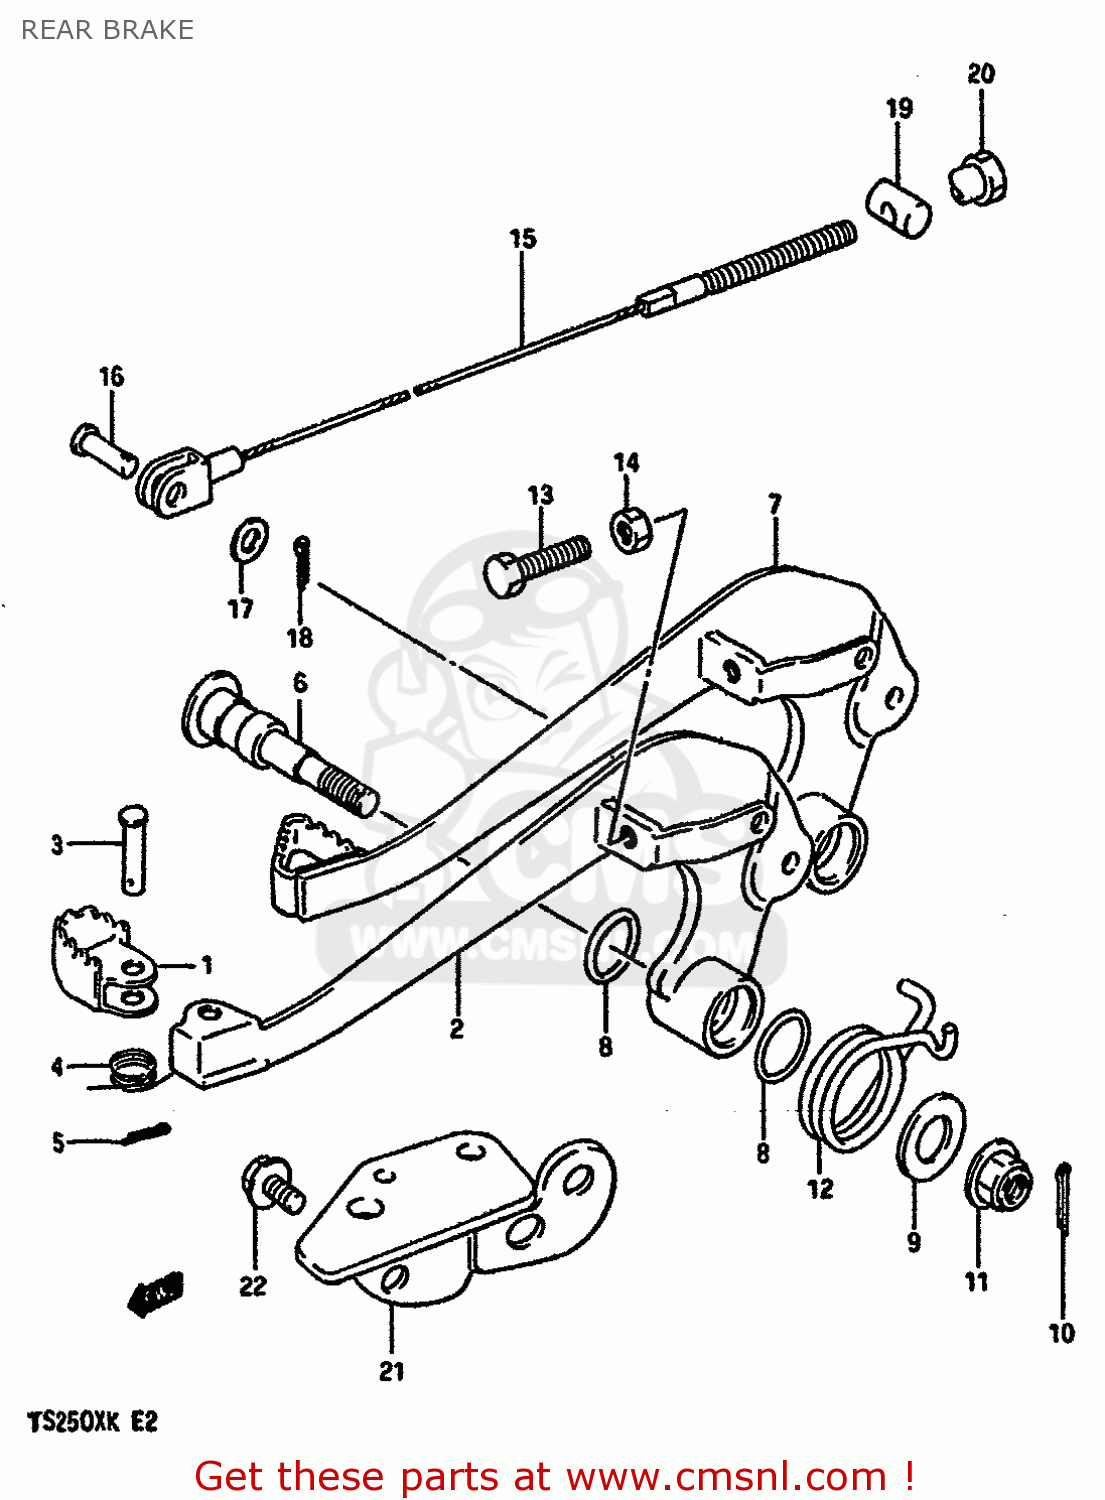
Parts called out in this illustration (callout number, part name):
1	PEDAL,BRAKE
2	ARM,BRAKE PEDAL
3	PIN
4	SPRING
5	PIN
6	SHAFT,BRAKE PEDAL
7	PEDAL,BRAKE
8	O RING(D:1.9,ID:14.5)
9	WASHER 10MM
10	PIN 20X20
11	NUT
12	SPRING
13	BOLT(6X23)
14	NUT 6MM
15	CABLE,REAR BRAKE
16	PIN(L:17.5)
17	WASHER
18	PIN 20X20
19	PIN(11X18)
20	NUT (6MM)
21	PROTECTOR,BRAKE PEDAL
22	BOLT
